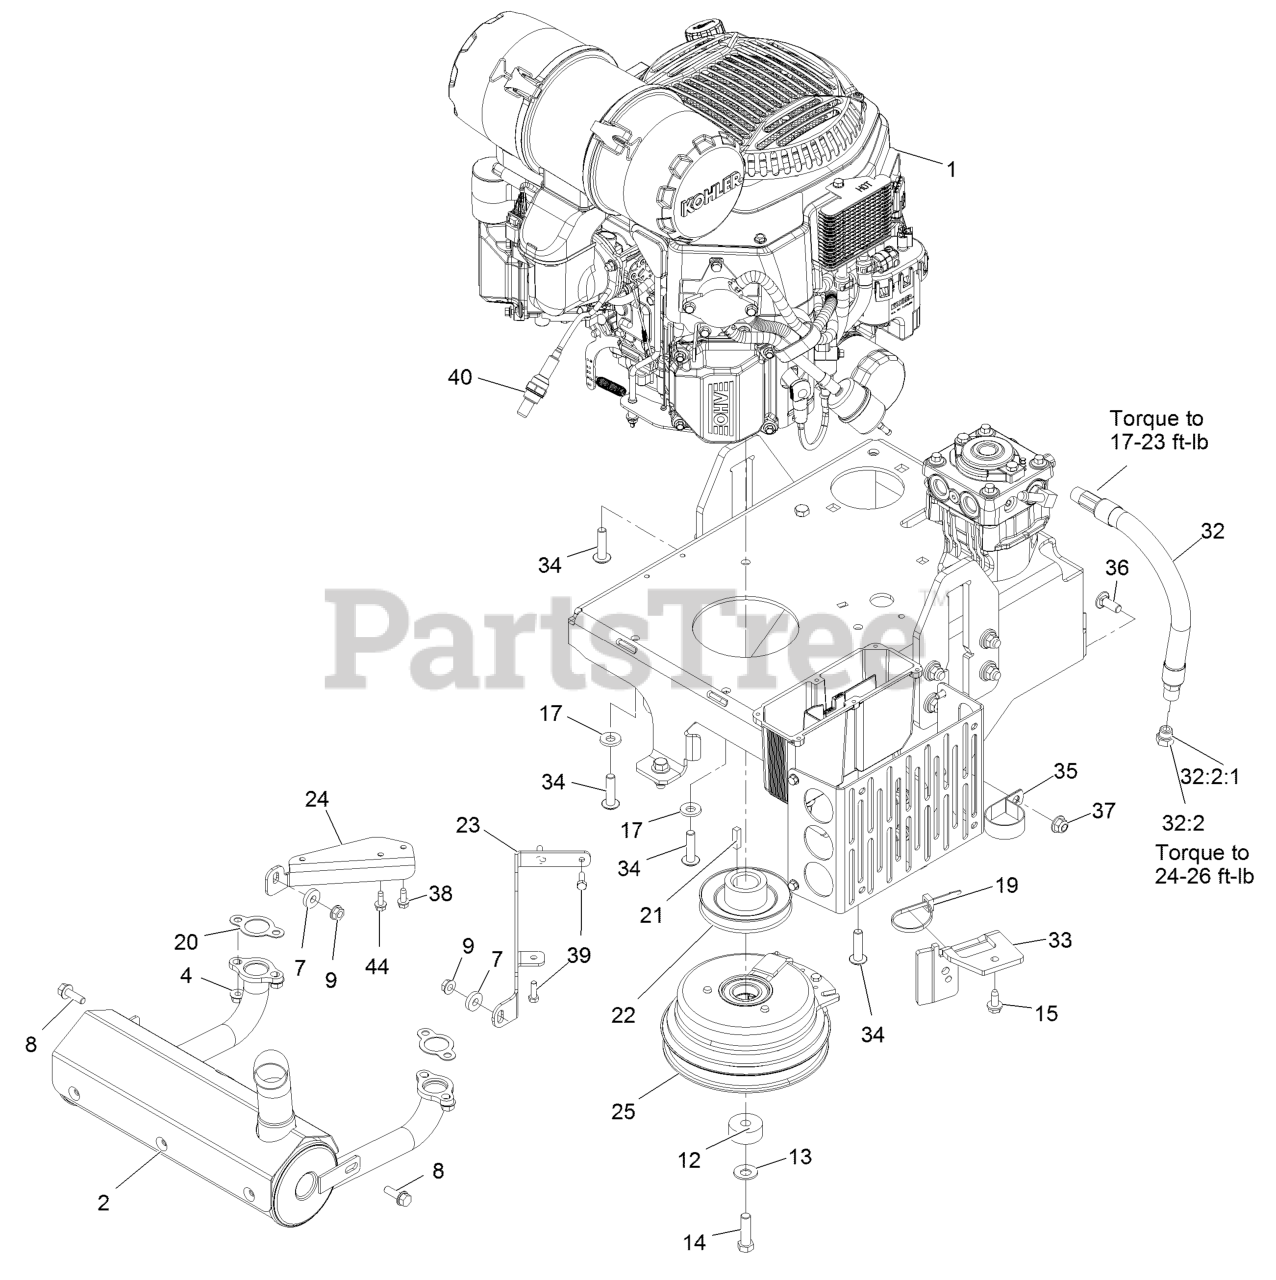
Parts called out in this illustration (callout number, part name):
4	NUT-FLANGE
8	SCREW-HHF
12	KEEPER-CLUTCH
13	WASHER-SPRING
14	SCREW-HH
15	Screw-HWH 5/16-18 X 3/4 Tf
17	WASHER-BELLEVILLE
19	TIE-CABLE
20	GASKET-EXHAUST
23	MOUNT, MUFFLER-LT
24	MOUNT, MUFFLER-RT
25	CLUTCH-200 FT-LB, 1.125 B
32	OIL DRAIN HOSE ASM
32:2	PLUG-HH
32:2:1	O-RING
33	BRACKET-ANCHOR, CLUTCH
34	SCREW-BHTF
35	CLAMP-R
36	SCREW-CARR
37	NUT-HF, NI
38	SCREW-HWHTF
39	SCREW-HH M6-1 X 20Mm W/Patch
40	SENSOR-OXYGEN
44	SCREW-HWHTF
